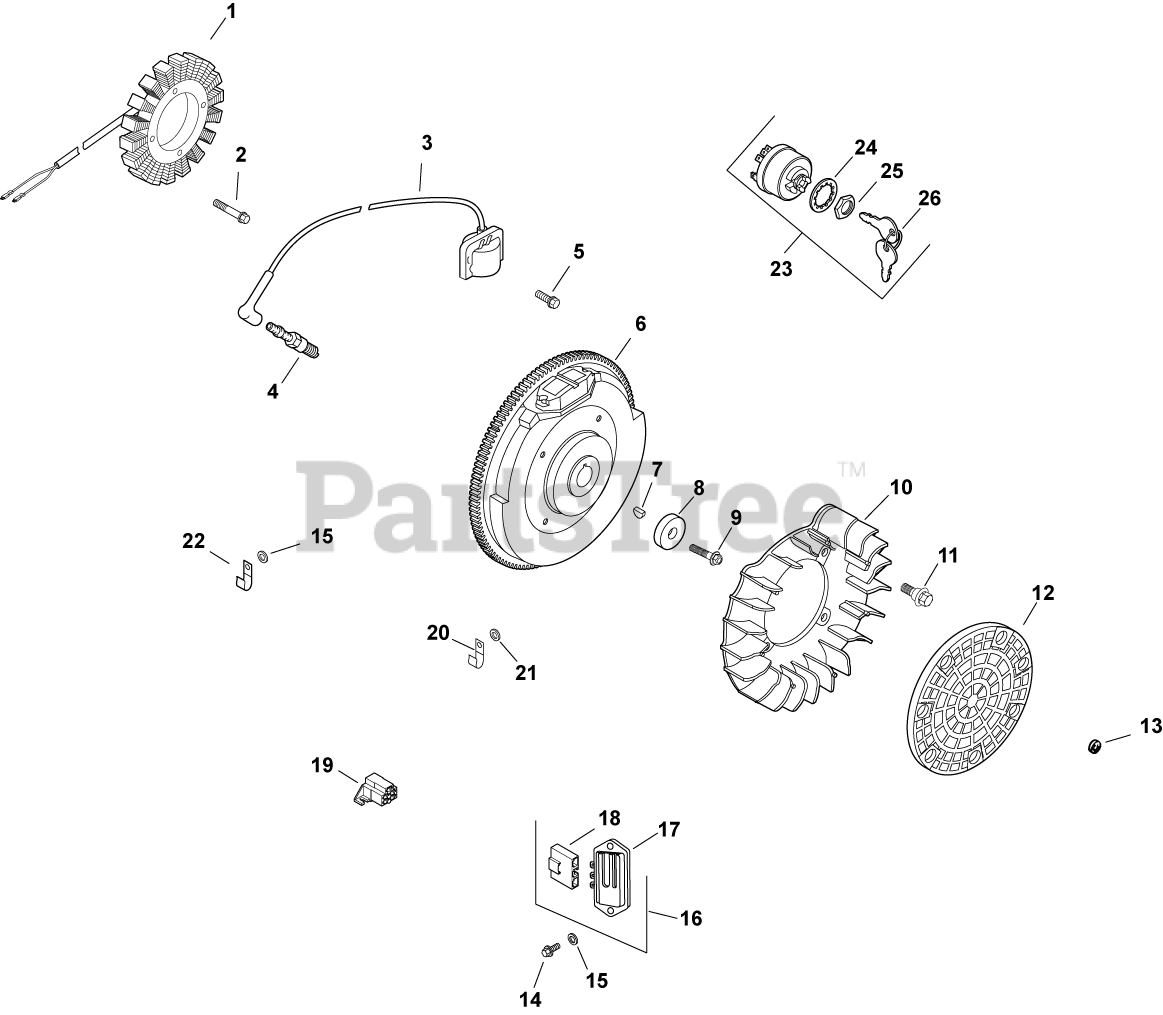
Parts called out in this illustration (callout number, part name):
1	KIT, 25 AMP STATOR ASSY.
2	SCREW, THD FROM M5X0.8X30
3	KIT, MODULE IGNTN (CDI FIXED)
4	PLUG, SPARK (STD)
5	SCREW, FLG THD FRM M5X.8X20-(#25086399S)
6	FLYWHEEL, PAINTED-USE 24 025 55-S
7	KEY, 3/16" X 5/8"
8	WASHER, FLAT 13/32"
9	SCREW, FLG M10X1.5X45 - (#25086361S)
10	FAN - USE (#24 157 11-S)
11	BOLT, SHOULDER
12	SCREEN, GRASS
14	SCREW, PHL HD #11-16X7/8"
15	WASHER, FLAT 7/32"
16	KIT, FULL WAVE CONVERSION
17	REG/RECTIFIER (20/25 AMP)-USE 25 403 20-
18	CONNECTOR, BODY (KM)-USE 25 155 41-S
19	CONNECTOR
20	CLIP, TUBE & WIRING (KM)
21	WASHER, FLAT 1/4" (O.D. 1/2")
22	CLIP, CABLE
23	SWITCH ASSY, KEY (KM)-USE 25 099 32-S
24	WASHER, INTERNAL TOOTH
25	NUT, KEY SWITCH
26	KEY, SET -USE 48 340 01-S
